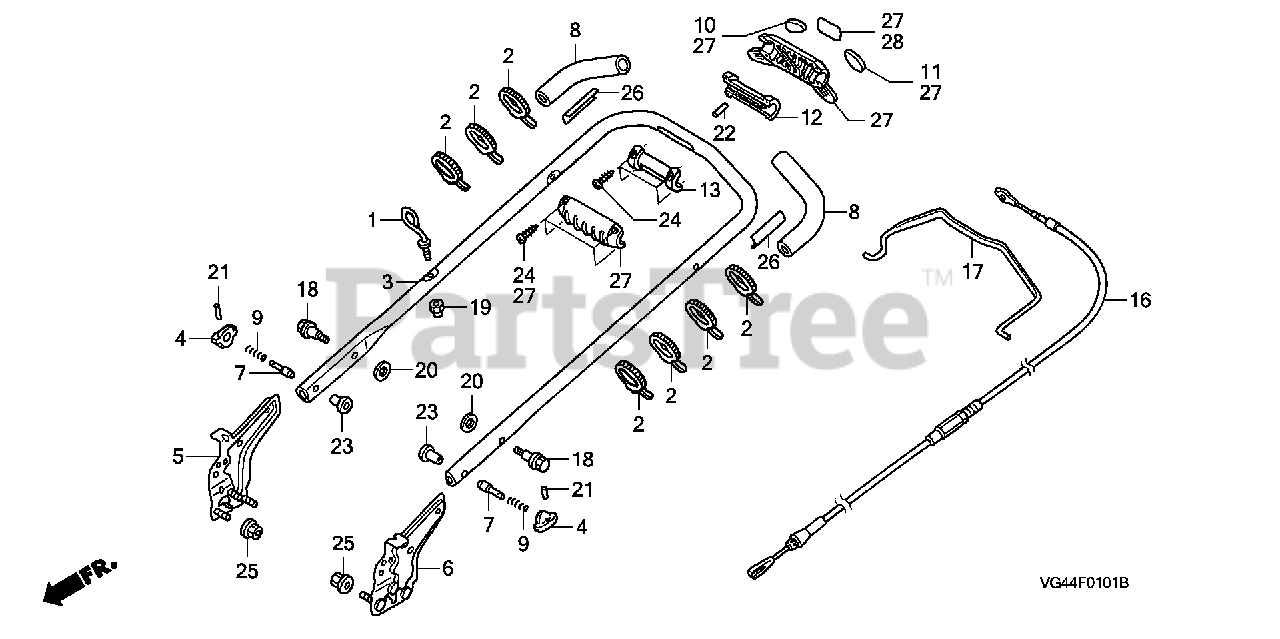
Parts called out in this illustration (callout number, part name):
1	GUIDE, ROPE
2	TIE, CABLE (157.5MM)
3	PIPE, HANDLE *NH105* (MAT BLACK)
4	GRIP, HANDLE JOINT *NH164* (GRIP GRAY)
5	STAY, R. HANDLE
6	STAY, L. HANDLE
7	PIN (8MM)
8	GRIP, HANDLE
9	SPRING, HANDLE ADJUSTING
10	GRIP, R. PAD
11	GRIP, L. PAD
12	BRACKET, GRIP (UPPER)
13	BRACKET, GRIP (LOWER)
16	CABLE, CLUTCH
17	LEVER, ROTO-STOP
18	BOLT, SPECIAL (8X32)
19	NUT, NYLON LOCK (6MM)
20	WASHER (25MM)
21	PIN, COILED (2X12)
22	ROLLER (5X37)
23	COLLAR, HANDLE HEIGHT ADJUSTING
24	SCREW, TAPPING (4X12)
25	NUT, FLANGE (8MM)
26	HOLD, GRIP
27	GRIP KIT, CLUTCH
28	MARK, CLUTCH INDICATION (ENGLISH)
